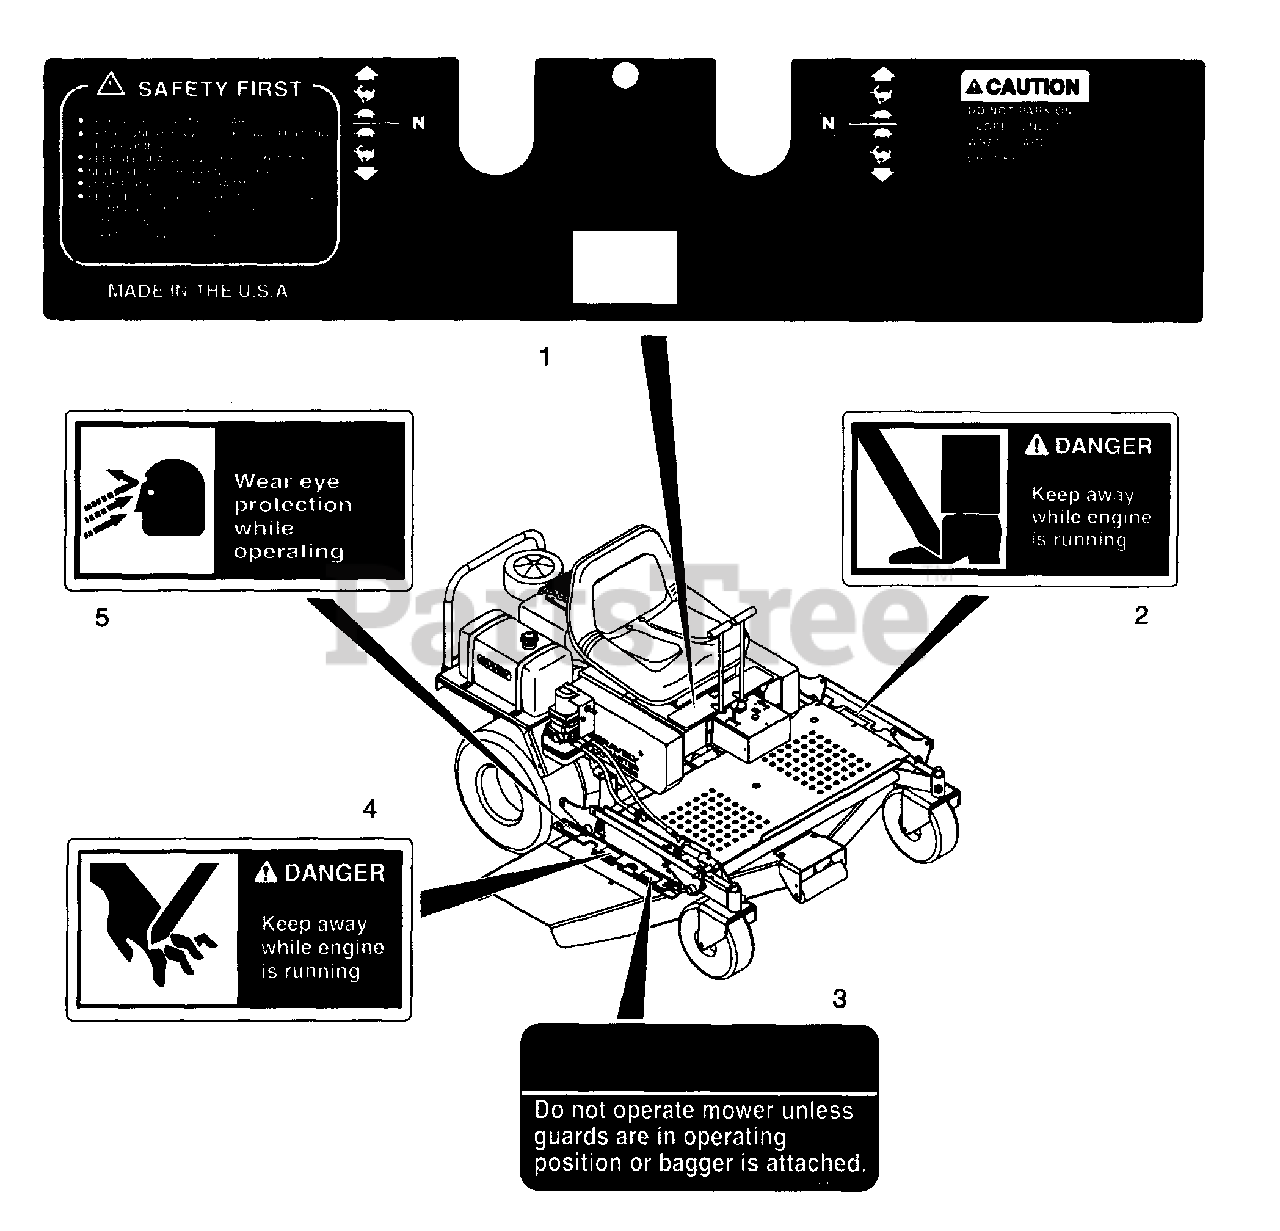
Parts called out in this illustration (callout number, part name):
1	Decal, Control Panel
2	Decal, Danger Foot
3	Decal - Warning
4	Decal, Danger Hand
5	Decal, Warning Eye
